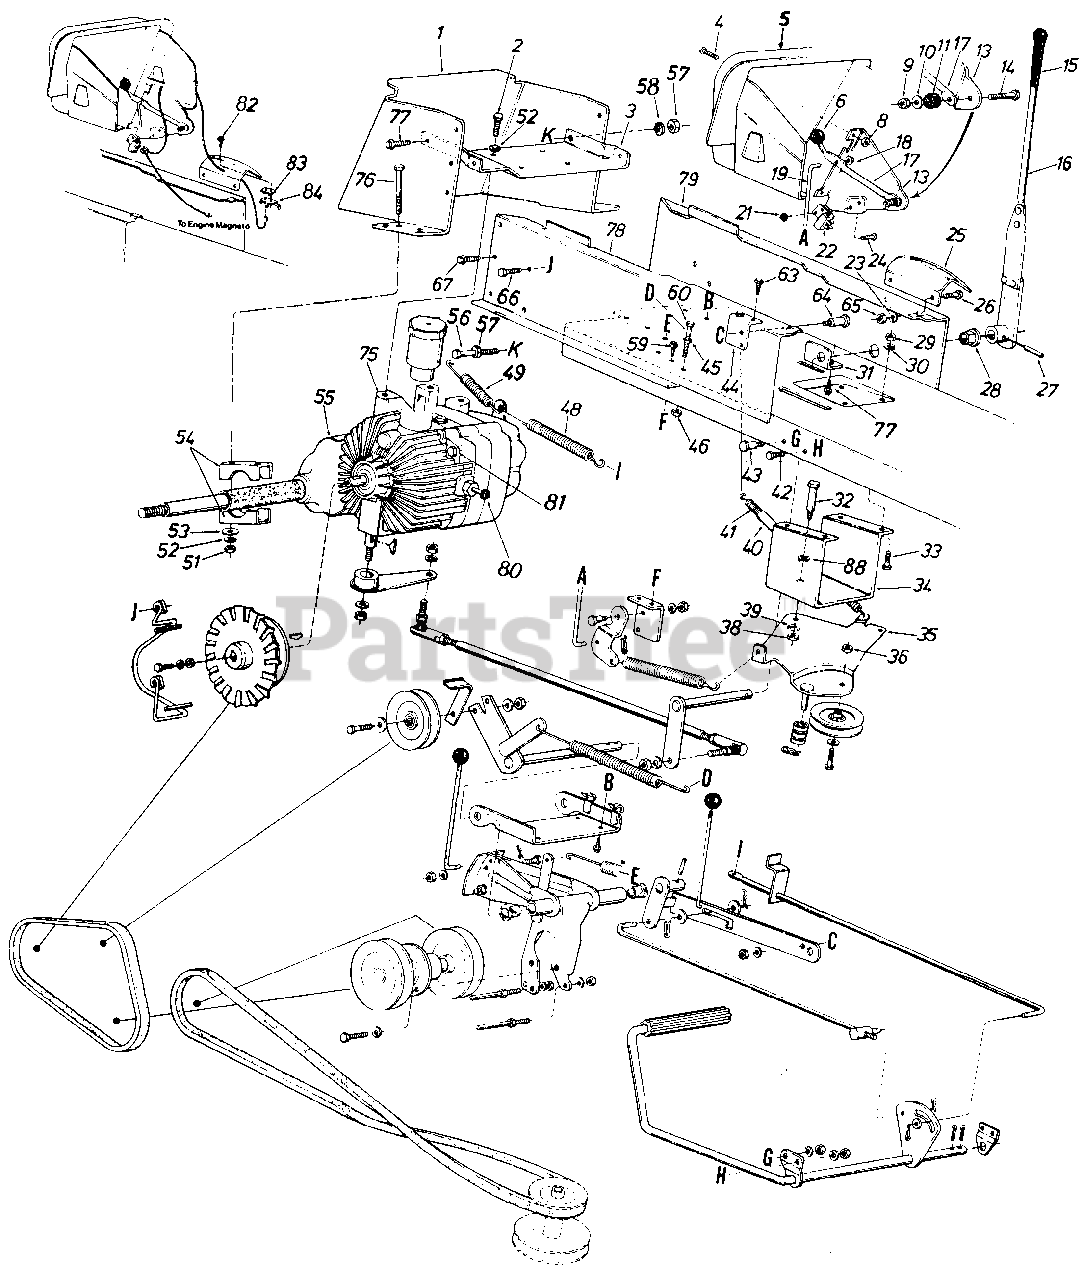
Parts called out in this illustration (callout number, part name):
1	Hitch Plate
2	Hex Bolt 3/8-16 x .75" Lg.*
3	Rear Axle Support Brkt.
4	Truss Mach. Scr. 1/4-20 x .50" Lg.*
5	Dash Panel Ass'y.
6	Knob Blade Clutch
8	Hex Sems Nut 1/4-20 Thd.
9	Hex Cent. L-Nut 1/4-20 Thd.
10	Fl-Wash. .28" I.D. x .74" O.D. x .063
11	Rubber Wash. .33" I.D. x .87" O.D. x 30
13	Deck Clutch Cont. Brkt.
14	Hex Bolt 1/4-20 x 1.25" Lg.*
15	Grip
16	Control Arm Ass'y.
17	Blade Clutch Lever
18	Push Nut 1/4" O.D. Rod
19	Deck Control Rod
21	Hex Nut #10-24 Thd.*
22	Safety Switch
23	L-Wash. 5116" I.D.*
24	Truss Mach. Scr. #10-24 x .50" Lg.*
25	Speed Control Bracket
26	Hex Bolt 5/16-18 x .62" Lg.*
27	Spring Pin Spiral 1/4" Dia. x 1.5" Lg.
28	Hex Flange Brg.
29	Hex Nut 5/16-18 Thd.*
30	L-Wash. 5/16" I.D.*
31	Speed Control Shaft Brkt.
32	Shld. Scr. .437" Dia. x .162" Lg.
33	Hex Bolt 5/16-18 x 1.00" Lg.*
34	Idler Support Brkt.
35	Idler Brkt. Ass'y.
36	Hex L-Nut 3/8-16 Thd.
38	Hex Nut 5/16-18 Thd.
39	L-Wash. 5/16" I.D.*
40	Convoluted Conduit .50" I.D.
41	Ext. Spring .50" O.D. x 6.37" Lg.
42	Hex Bolt 3/8-16 x .62" Lg.*
43	Shld. Scr. .50" Dia. x .395" Lg. (3/8-16)
44	Parking Brake Cam Mtg. Brkt.
45	Hex Nut 5/16-28 Thd.
46	Hex L-Nut 5/16-18 Thd.
48	Brake Tension Spring
49	Ext. Spring Brake Return
51	Hex Nut 3/8-16 Thd.
52	L-Wash. 3/8" I.D.
53	Fl-Wash. .390" I.D. x 1.00" O.D. x .125" Thk.
54	Rear Axle Bracket
55	Transaxle
56	Hex Bolt 1/4-20 x 2" Lg.
57	Hex Nut 1/4-20 Thd.
58	L-Wash. 1/4" I.D.
59	Hex Wash. Hd. Self-Tap Scr. 1/4-20 x .50" Lg.
60	Hex Bolt 5/16-18 x 1.50" Lg.
63	Hex Wash. Hd. Self-Tap Scr. 1/4-20 x .50" Lg.
64	Shld. Scr. .437" Dia. x .162" Lg.
65	Hex Nut 5/16-18 Thd.
66	Hex Wash. Hd. Scr. 3/8-16 x .50" Lg.
67	Hex Wash. Hd. Self-Tap Scr. 5/16-18 x .75" Lg.
75	Hydrostatic Pump Comp.
76	Hex Bolt 3/8-16 x 3.5" Lg.
77	Hex AB-Tap Scr. 5/16 x .75" Lg.
78	Side Panel Upper Frame R.H.
79	Side Panel Upper Frame L.H.
80	Cap
81	Socket Hd. Bolt 3/8-16 x 2.75" Lg.
82	Hex Wash. Hd. Scr. #8 x .50" Lg.
83	Insulator Nut Plate
84	Spring Switch
88	Wave Washer
